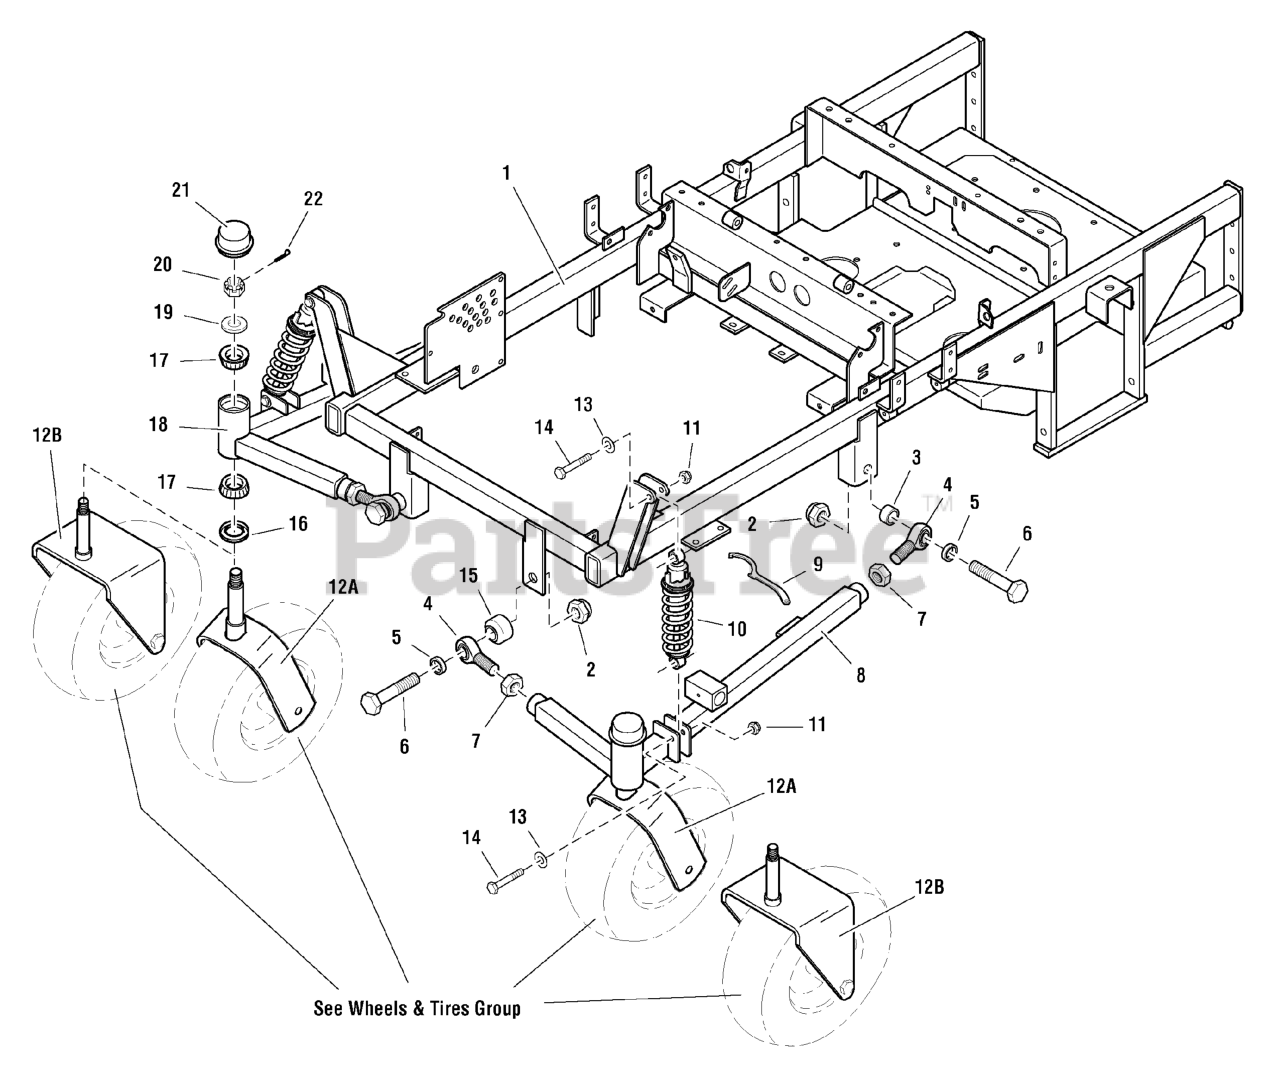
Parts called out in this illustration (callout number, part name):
1	MAIN FRAME (see footnote)
2	NUT, 3/4-16 Hex Nylon Lock
3	SPACER, .76 x 1.00 x .50
4	BALL JOINT, 3/4-16 Male
5	SPACER, .76 x 1.00 x .25
6	BOLT, 3/4-16 x 3-1/2
7	NUT, 3/4-16 Hex Jam
8	ASSM, A-ARM, LH
9	WRENCH, SPANNER, CZ
10	SHOCK & SPRING ASSEMBLY
11	NUT, 3/8-16 HEX NYLON LOCK
12A	CASTER YOKE
12B	CASTER TIRE MOUNT
13	WASHER, 3/8 SAE
14	BOLT, 3/8-16 X 2-1/4" GD5 CZ
15	SPACER, .75 x 1.50 x 1.00
16	SEAL, GREASE
17	BEARING, Tapered Roller
18	SUSPENSION ARM ASSEMBLY - RH
19	WASHER, 3/4 SAE
20	NUT, 3/4-16 Hex Slotted
21	CAP
22	PIN, COTTER, 1/8 X 1-1/4
